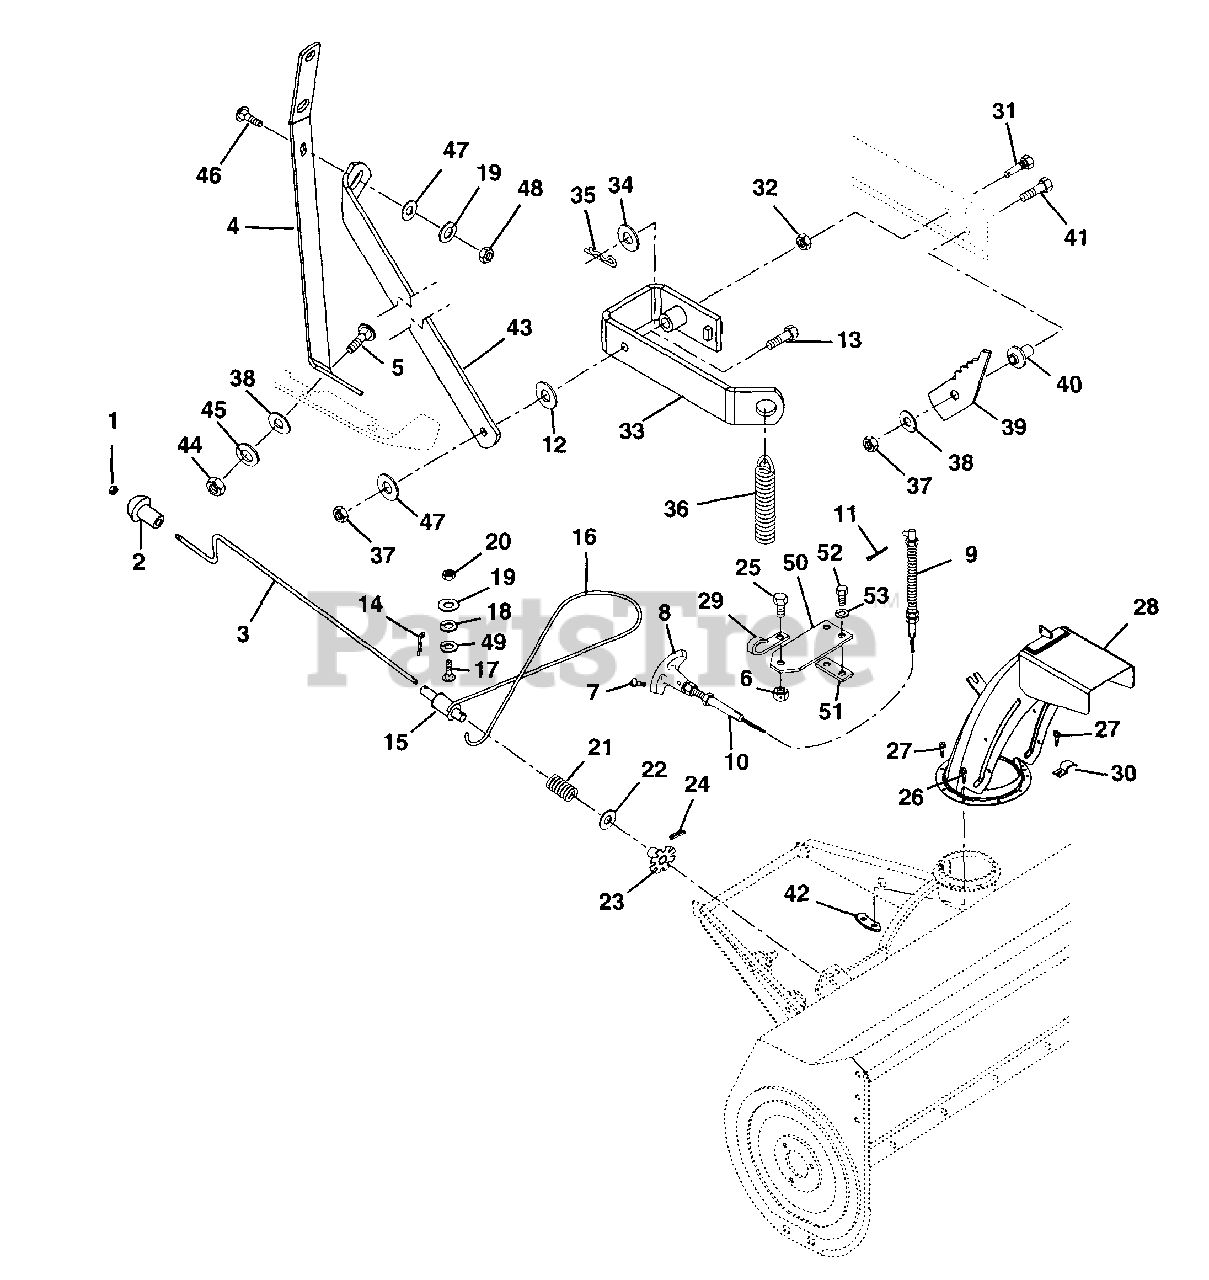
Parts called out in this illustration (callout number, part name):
1	Nut-Locking-Jam-Center .375-16
2	Knob
3	Chute Control Crank
4	Support-Rod
5	Bolt-Round Head Square Neck .38-16 x 1.0
6	Nut-Locking-Center .38-16
7	Screw-Machine-Hex-Washer Head 8-32 x .75
8	Knob-Black
10	Control Cable
11	Pin-Center .09 x .75
12	Washer-Flat-Steel .38 x .875 x .083
13	Bolt-Hex .31-18 x 1.00 Grade 5
14	Pin-Hair Internal .08 x .38 x 1.42
15	Spool
16	Cable
17	Bolt-Round Head Square Neck .25-20 x .75 Grade 5
18	Washer-Flat-Steel .281 x .620 x .065
19	Washer-Locking-External .262 x .502 x .026
20	Nut-Hex .25-20
21	Spring-Comp .054 x .75 x 1.6
22	Washer-Flat-Steel .656 x 1.31 x .095
23	Disc Assembly
24	Pin-Roll .188 x 1.00
25	Bolt-Hex .38-16 x .50 Grade 5
26	Screw-Tapping 12-24 x .50
27	Screw-Tapping 12-24 x .75
28	Deflector w/Decal
29	J-Clamp
30	Cable Clamp
31	Stud-Weight
32	Nut-Locking-Center .50-13
33	Spring Arm
34	Nut-Hex-Jam .375-16
35	Pin-Hair Internal .08 x .18 x 1.18
36	Spring-Tens .188 x 1.50 x 8.5
37	Nut-Locking-Center .31-18
38	Washer-Flat-Steel .38 x .875 x .083
39	Spring Assist Control
40	Spacer
41	Bolt-Hex .31-18 x 1.25 Grade 5
42	Chute Clamp
44	Nut-Hex .375-16 Grade 2
45	Washer-Locking .375 x .094
46	Bolt-Round Head Square Neck .31-18 x 1.00 Grade 5
47	Washer-Flat-Steel .344 x .688 x .065
48	Nut-Hex .31-18
49	Washer-Locking .31 x .062
50	Bracket-Cable Holder
51	Plate-Cable Holder
52	Bolt-Hex .25-20 x .50 Grade 5
53	Washer-Locking .25 x .062
